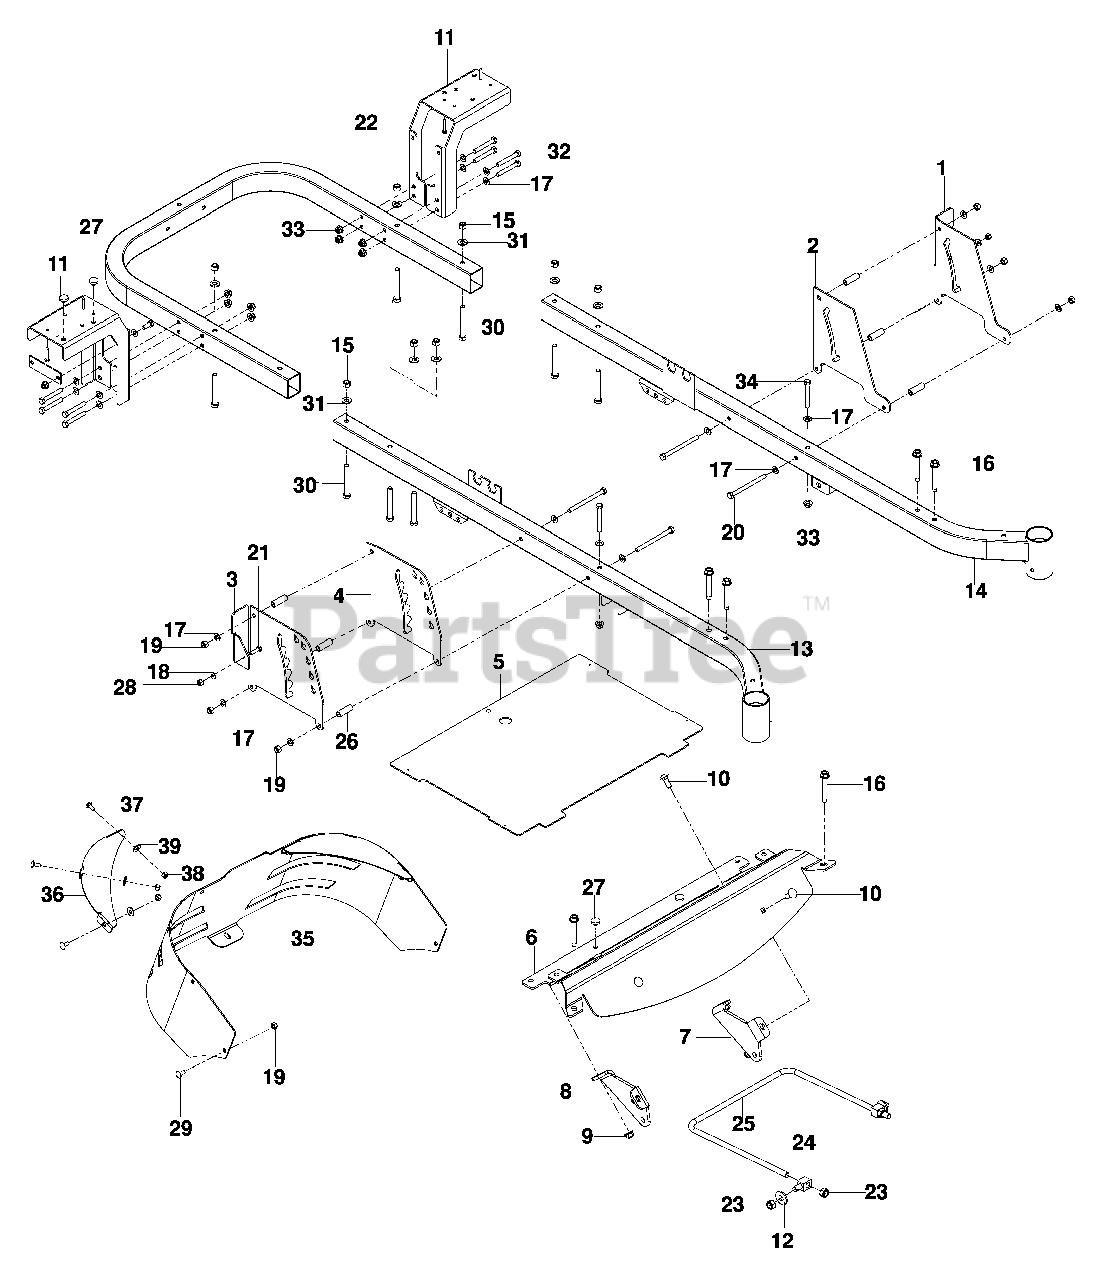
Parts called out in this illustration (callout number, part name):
1	PLATE, OUTER BRAKE
2	PLATE, BRAKE LATCH
3	PLATE, OUTER HEIGHT
4	PLATE, INNER HEIGHT
5	FOOT PLATE w/DECALS
7	MOUNT, STRUT, RT
8	MOUNT, STRUT, LT
9	NUT 3/8-16 HEX FLG NYLOC
10	RHSNB 3/8-16 x 1
11	SUPPORT, FENDER
12	WASHER ½ FLAT
13	FRAME, FRONT RT
14	FRAME, FRONT LT
15	NUT 3/8-16 HEX NYLOC
16	BOLT 3/8-16 x 25/8 THD FRM
17	WASHER 5/16 SAE FLAT
18	WASHER ¼ FLAT SAE
19	NUT 5/16-18 HEX NYLOC
20	HCS 5/16-18 x 4
21	HCS ¼-20 x 1
22	SCREW 10-12 x 1¼ WSH HD
23	NUT 7/16-14 HEX NYLOC
25	LINK, FRONT SUSPENSION
26	SPACER ½ OD x 1½
27	GROMMET, BUMPER
28	NUT ¼-20 HEX NYLOC
29	RHSNB 5/16-18 x ¾
30	HCS 3/8-16 x 3
31	WASHER 3/8 SAE FLAT
32	HCS 5/16-18 x 2¼
33	NUT 5/16-18 FLANGE NYLOC
34	HCS 5/16-18 x 2¾
35	GUARD, WIDE ENGINE
36	SUPPORT, CORNER
37	RHSSNB ¼-20 x 5/8
38	NUT ¼-20 HEX NYLOC
39	WASHER ¼ FLAT
